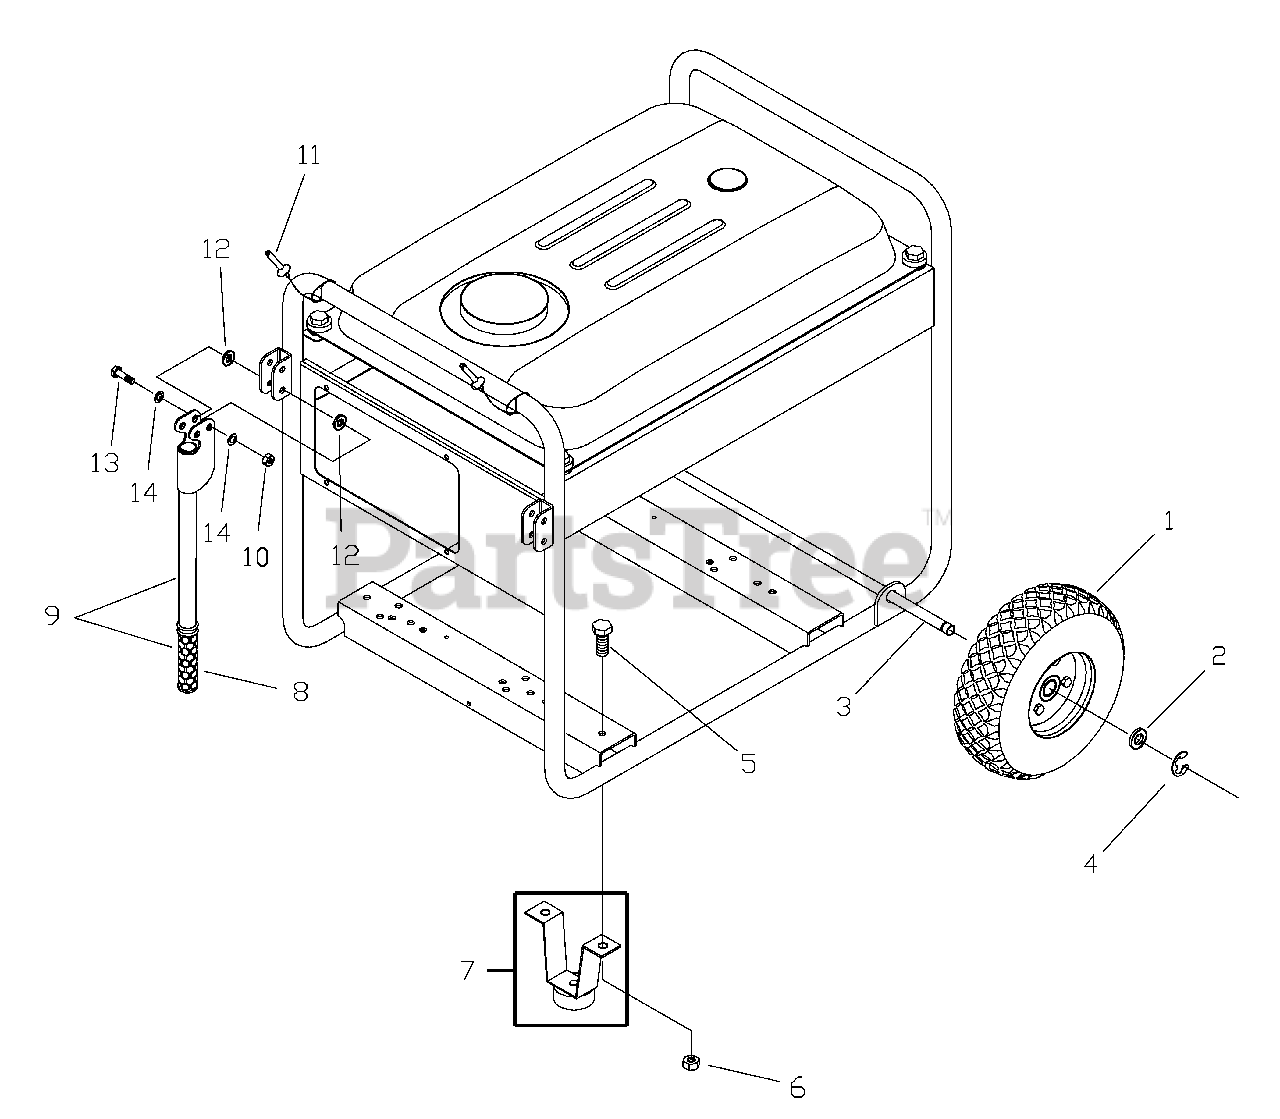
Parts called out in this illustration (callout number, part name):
1	Wheel
2	Washer, 5/8"
4	E-Ring
5	HHCS, M8 1.25 x 20
6	Nut, M8, Flange Serrated
9	Assy, Handle w/Grip
10	Nut, M8 - 1.25, Nylok
12	Washer, 1.2 x 0.346 x 0.03, Nylon
13	HHCS, M8 - 1.25 x 45
14	Washer, Flat, 5/16 - M8
